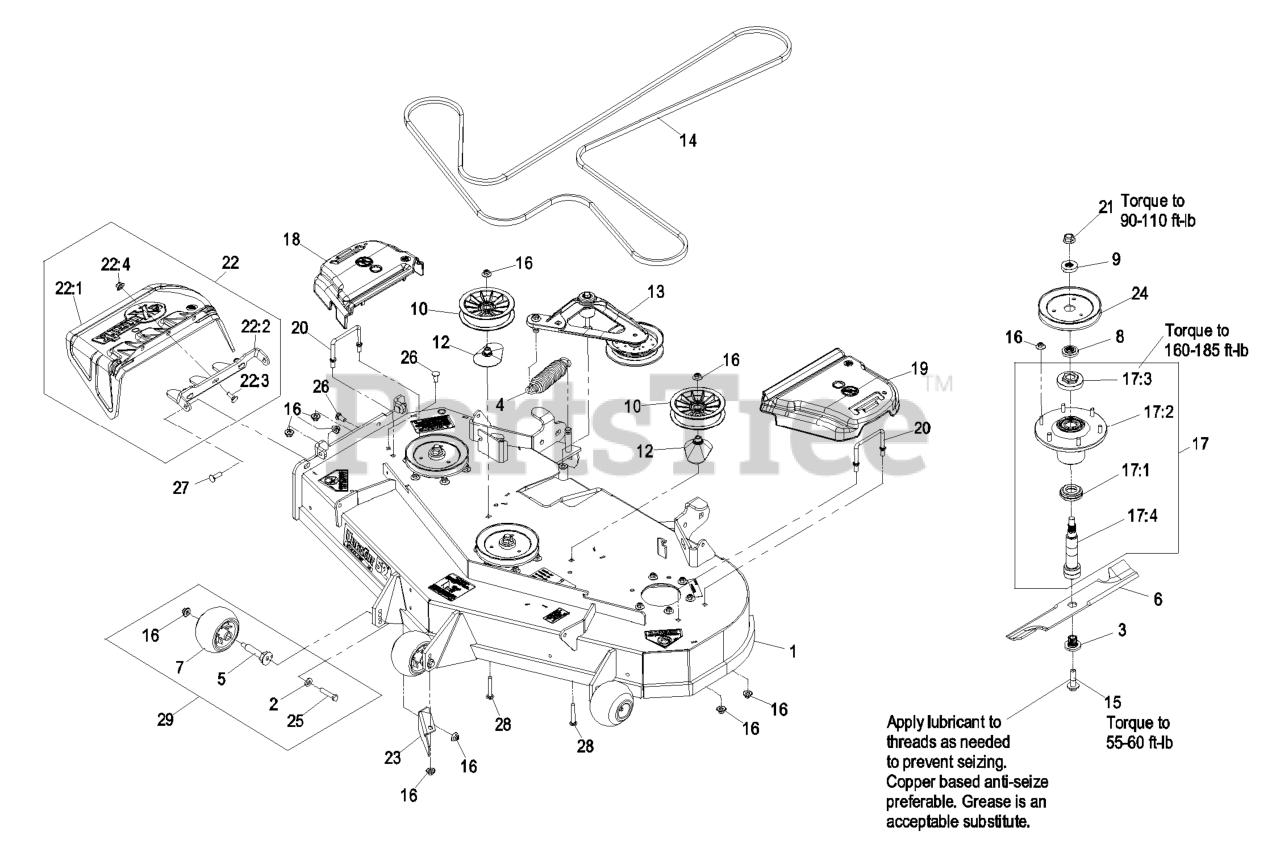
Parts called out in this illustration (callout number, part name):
1	ASM,DECK W/ DECALS 52
2	WASHER-BELLEVILLE
3	BUSHING,SPLINED
7	ROLLER-SCALP, ANTI
8	SPACER,SPLINED STEPPED
9	SPACER,SPLINED
10	PULLEY,IDLER 5"
12	SPACER-PULLEY
14	BELT,V-B X 186.00"
15	SCREW,SEMS 1/2-20 X 2.19
16	Nut-Nyloc 3/8-16 Flg
17	ASM,SPINDLE HOUSING
17:1	GUARD,BOTTOM
17:2	ASM,CUTTER HOUSING
17:3	NUT, SPINDLE 7/8-14
17:4	SPINDLE,DOUBLE SPLINE
18	COVER-BELT, RH
19	COVER-BELT, LH
20	WIREFORM-COVER
21	NUT-FLANGE, CENTERLOCK
22	ASM,DISCHARGE CHUTE
22:1	CHUTE,DISCHARGE
22:2	BRACKET,DISCHARGE CHUTE
22:3	SCREW-CARR
22:4	Nut-Nyloc 3/8-16 Flg
23	BAFFLE,DISCHARGE 52/60
24	SHEAVE,BLADE DRIVE
25	SCREW-HH
26	SCREW-CARR
27	Bolt-Carriage 3/8-16 X 1 1/4
28	SCREW-CARR
30	Asm, Deck Complete 526
